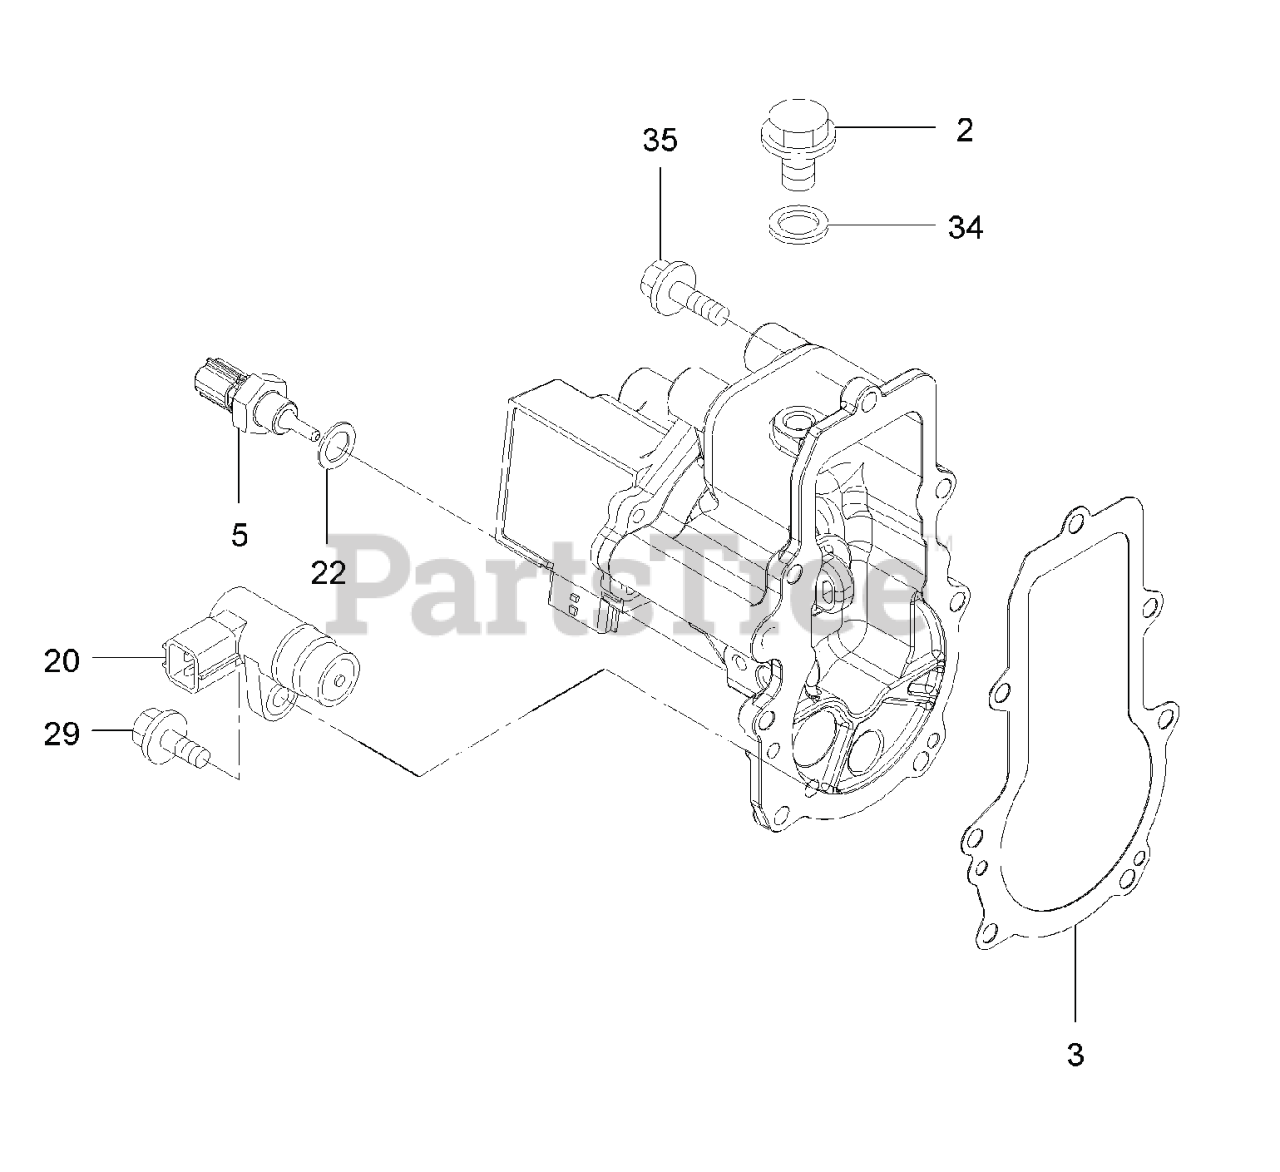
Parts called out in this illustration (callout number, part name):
5	SENSOR-OIL TEMP
22	WASHER-SEAL
34	WASHER-SEAL
